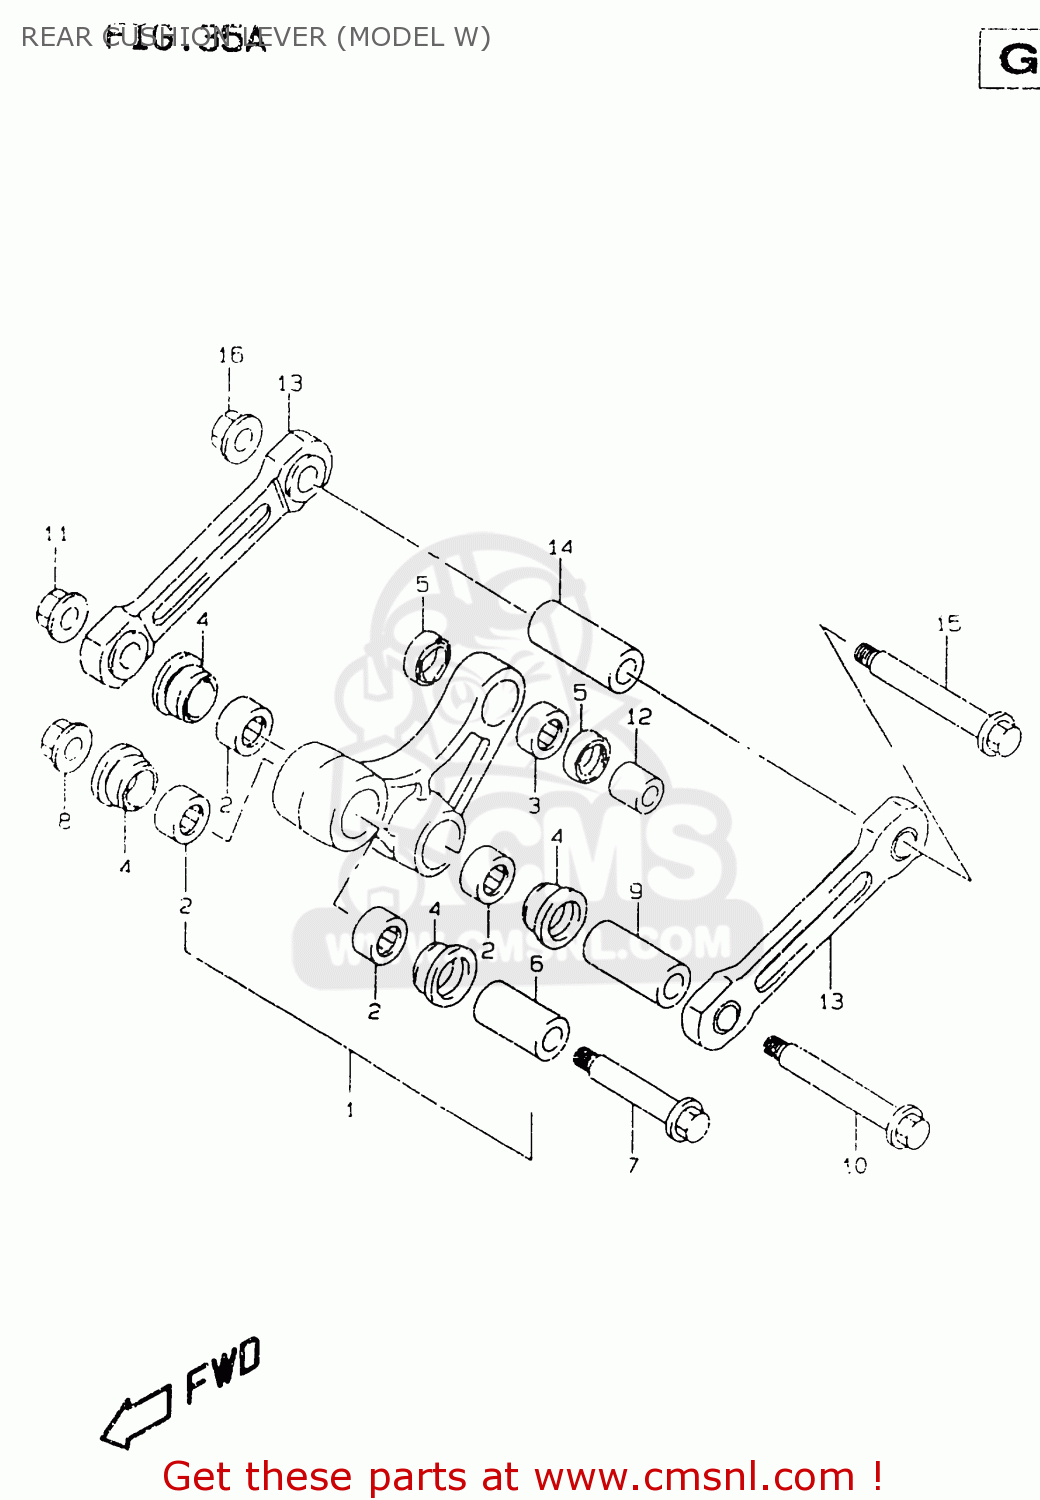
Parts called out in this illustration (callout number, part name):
1	LEVER SET,RR CUSHION
2	BEARING(22X28X16)
3	BEARING(20X26X12)
4	SEAL,SWINGING ARM RR
5	SEAL,OIL(20X26X4.5)
6	SPACER,RR CUSHION LEVER FR
7	BOLT,REAR CUSHION LEVER
8	NUT 12MM
9	SPACER,RR CUSHION
10	BOLT,REAR CUSHION
11	NUT 12MM
12	SPACER,RR CUSHION LEVER RR
13	ROD SET,REAR CUSHION
14	SPACER,RR CUSHION
15	BOLT,REAR CUSHION
16	NUT 12MM
